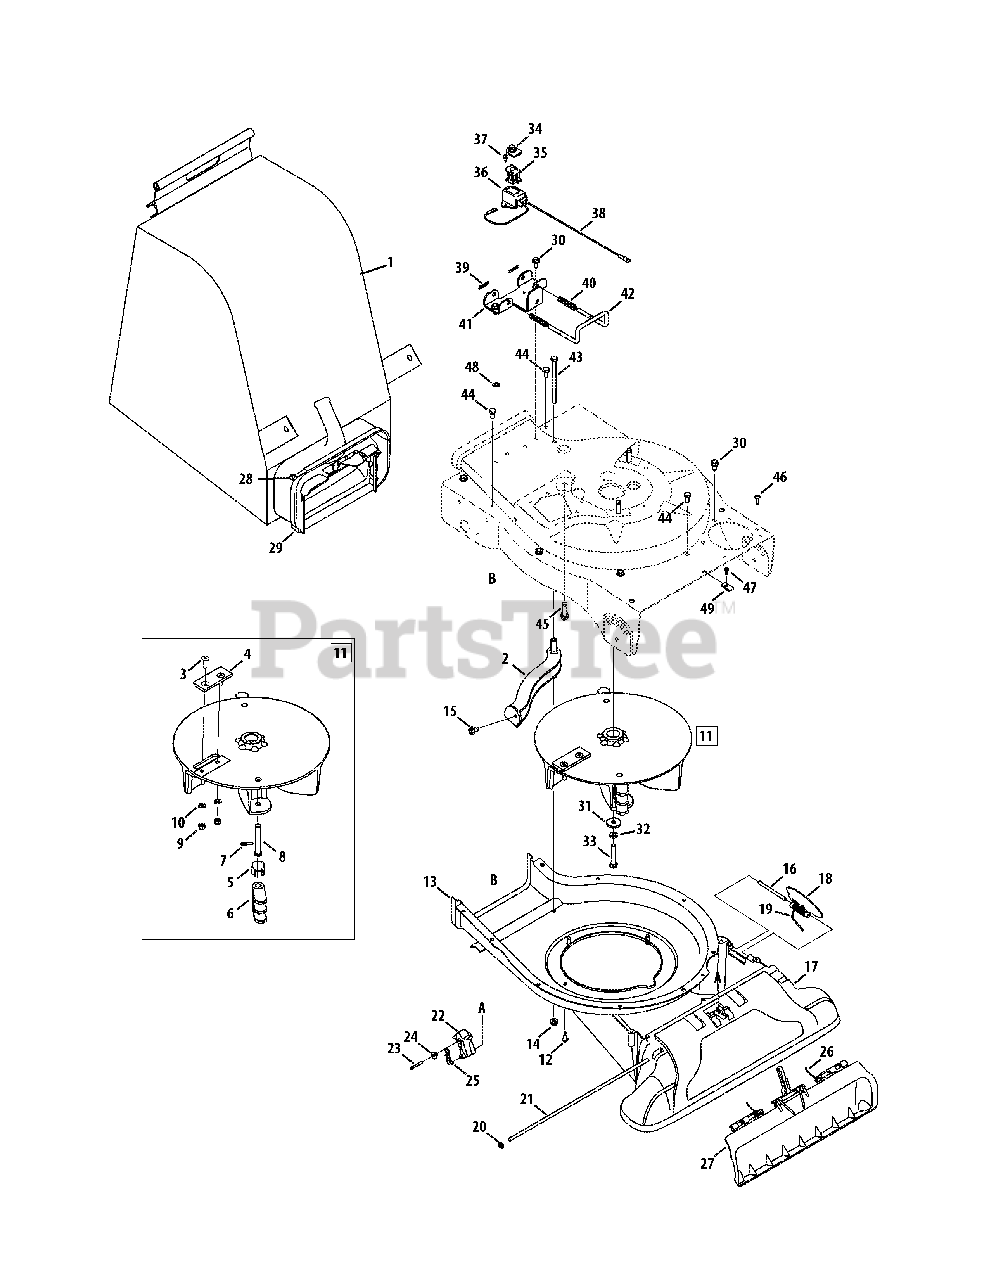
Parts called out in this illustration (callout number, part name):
1	Bag Assembly (incl. Ref 28)
2	Screen Assembly
3	Hex Screw 5/16-24 x 1.0
4	Chipper Blade
7	Spiral Pin
8	Clevis Pin
9	Lock Nut, 5/16-24
10	Lock Washer, 5/16
11	Impeller Assembly (Incl. Ref.# 3 - 10)
11	Impeller Assembly
12	Shoulder Screw, #12-24 x.30 x.46
13	Lower Flail Housing
14	Flange Lock Nut 5/16-18
15	Screw, 5/16-18 x.500
18	Base Adapter Door
19	Torsion Spring
20	Cap Speed Nut 1/4
21	Pivot Rod
22	Nozzle Door Lever
23	Hex Screw, #8-18 x 1.25
24	Shoulder Spacer
25	Extension Spring
26	Nozzle Door Torsion Spring
27	Nozzle Door
28	Tie Strap, 42"
29	Chute Assembly
30	Hex Index Screw, 5/16-12 x.750
31	Flat Washer.375 ID x 1.25 OD
32	Lock Washer 3/8
33	Hex Cap Screw 3/8-24 x 2.0
34	Switch Cover
35	Safety Switch
36	Safety Switch Cover
37	Hex Washer Screw #10-16 x.50
38	Wire Harness
39	Cotter Pin
40	Compression Spring
41	Mounting Bracket
43	Hex Cap Screw 5/16-18 x 4.5
44	Hex Cap Screw 5/16-18 x.625
45	Hex Washer Screw 3/8-16 x 1.00
46	Screw, #12-16 x.750
47	Screw #10 - 16 x.500
48	External L-Washer 5/16
49	Speed Nut
